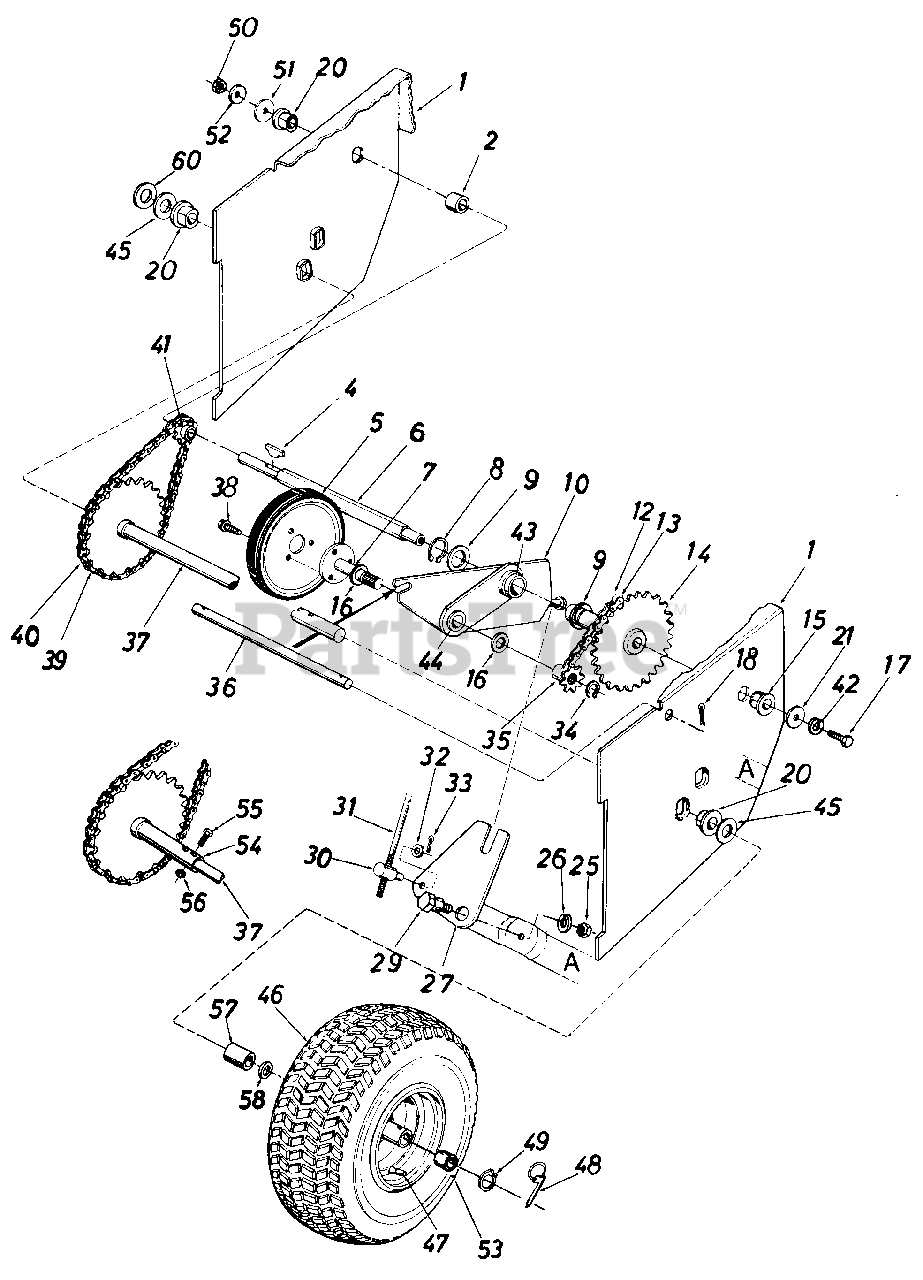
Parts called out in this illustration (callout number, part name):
1	Frame Ass'y.
2	Spacer.50" l.D. x 75" O.D. x.78 Lg.
4	#4 Hi-Pro Key 3/32 x 5/8" Dia.
5	Friction Wheel Ass'y.
6	Hex Shaft
7	Friction Wheel Mounting Plate Ass'y.
8	Snap Ring 1.00n Dia. Shaft
9	Fl-Wash. 1.00" x 1.63" O.D. x .03
10	Sliding Bracket Ass'y.
12	#41 Chain 1/2" Pitch x 35 Links
13	Master Link for #41 Chain
14	32 Teeth Sprocket Ass'y.
15	Hex Flange Brg. .630" I.D.
16	Fl-Wash. .62l1 I.D. x 1.00n O.D. x .06
17	Hex Lock Bolt 5/16-18 X .62" Lg.
18	Cotter Pin 3/32n Dia. x .75" Lg.
20	Flange Brg. w/Flats .756" I.D.
21	Fl-Wash. 34" l.D. x 1.12 0 O.D. x .125
25	Hex Jam Nut 3/8-16 Thd.
26	L-Wash. 3/8" I.D.
27	Shifting Linkage Bracket
29	Shld. Bolt .625" Dia. x 170n Lg.
30	Adjustment Ferrule
31	Shifting Rod 5/16n Dia. x 32 50" Lg .
32	Fl-Wash. 34n l.D. x .64 0 O.D. x .06
33	Cotter Pin 3/32n Dia. x .75" Lg.
34	Snap Ring .562n Dia. Shaft
35	Sprocket 7 Teeth x 50n Pitch
36	Shaft 50n Dia. x 9.50" Lg.
37	28 Teeth Wheel Axle Ass'y.
37	32 Teeth Wheel Axle Ass'y.
37	Wheel Axle
38	Hex Wash. Hd. Self-Tap Scr. 5/16-24 x .50" Lg.
39	#41 Chain 1/2" Pitch x 43 Links
39	#420 Chain 1/2" Pitch x 39 Links
40	Master Link for #41 Chain
40	Master Link for #420 Chain
41	8 Teeth Cooler Sprocket
42	L-Wash. 5/18" I.Ds
43	Bearing
44	Bronze Bearing
45	Fl-Wash. .76" .D. x 1.49 0 O.D.
45	Fl-Wash. .76" I.D. x 1.49
46	Wheel Ass'y. Comp. 13 x 5.0
46	Wheel Ass'y. Comp. 13 x 6.5
47	Air Valve
48	Klick Pin
49	Snap Ring .75 Dia.
50	Hex Ins. L-Nut 1/2-20 Thd.
51	Fl-Wash. .53 I.D. x 1.25 O.D. x .10
52	Bell-Wash. .50 I.D. x 1.0 O.D. x .075
53	Sleeve Brg.
54	32 Teeth Sprocket Hub Ass'y.
55	Hex Bolt 1/4-28 x 1.5"
56	Hex L-Nut 1/4-28 Thd.
57	Spacer
58	Fl-Washer
60	Fl-Washer
